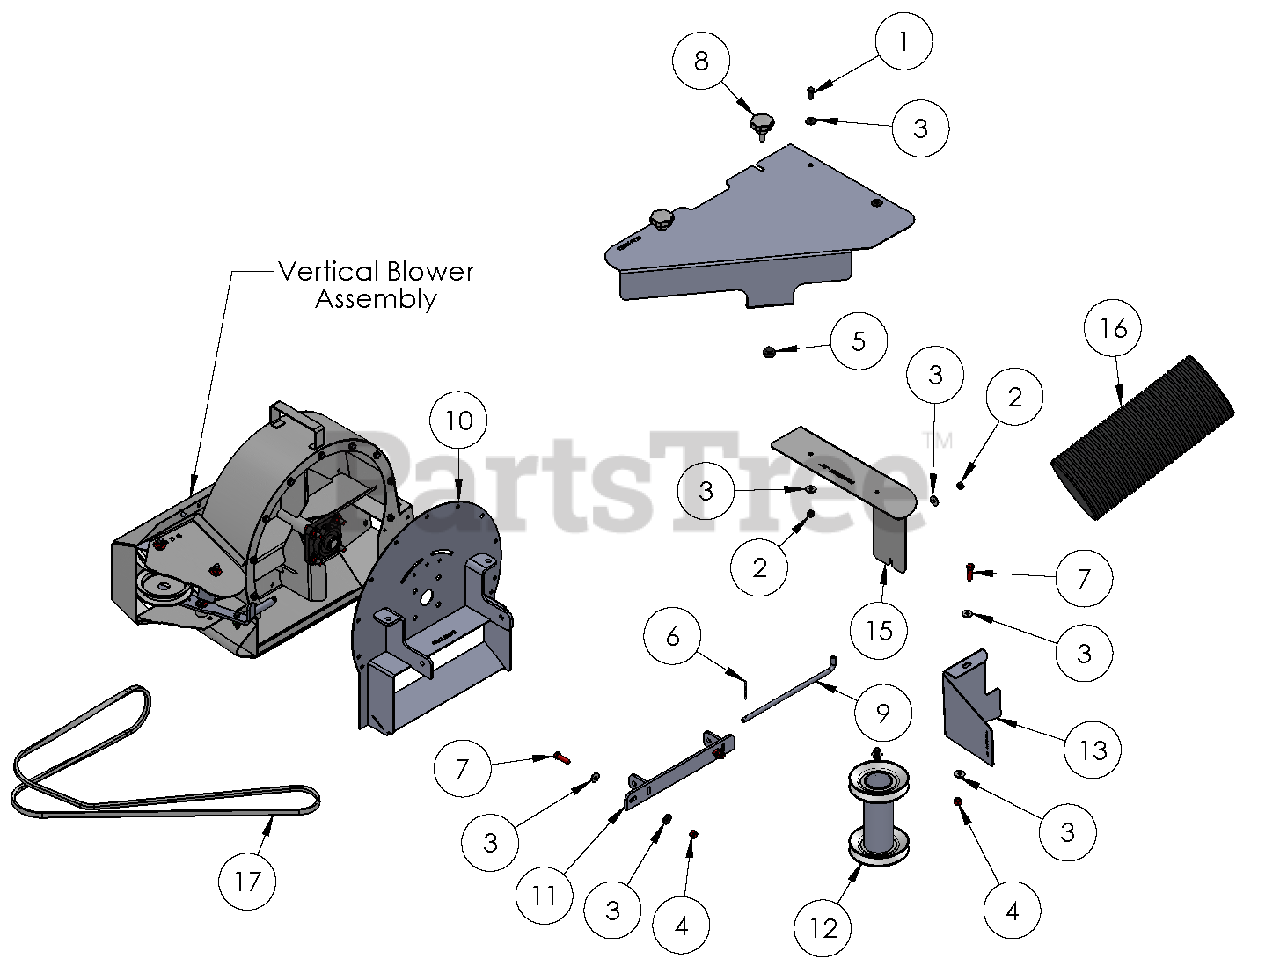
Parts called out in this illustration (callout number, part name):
1	@BLT-HEX .31-18X.75 GR5 YWZC
2	@NUT-LK-NYL-FLG .31-18 YWZC
3	@WSHR-FL-STL.344X.688X.065YWZC
4	@NUT-LK-NYL-FLG .38-16 YWZC
5	RUBBER BUMPER
6	HAIR PIN, 0.091 X 1.875
7	@BLT-HEX .38-16X1.25 GR5 YWZC
8	RELEASE KNOB
9	MOUNTING PIN, 'L' 10.25" EL
10	BLOWER MOUNT, PRO SERIES
11	DECK BRACKET, 60" PRO SERIES
12	DOUBLE PULLEY, PRO SERIES
13	DECK SEAL, 60" PRO SERIES
14	FRONT PULLEY COVER, PRO SERIES
15	PULLEY COVER LEG , 60" PRO
16	HOSE, 6" X 48" LG.
17	BELT, ARAMID CORD 105"
